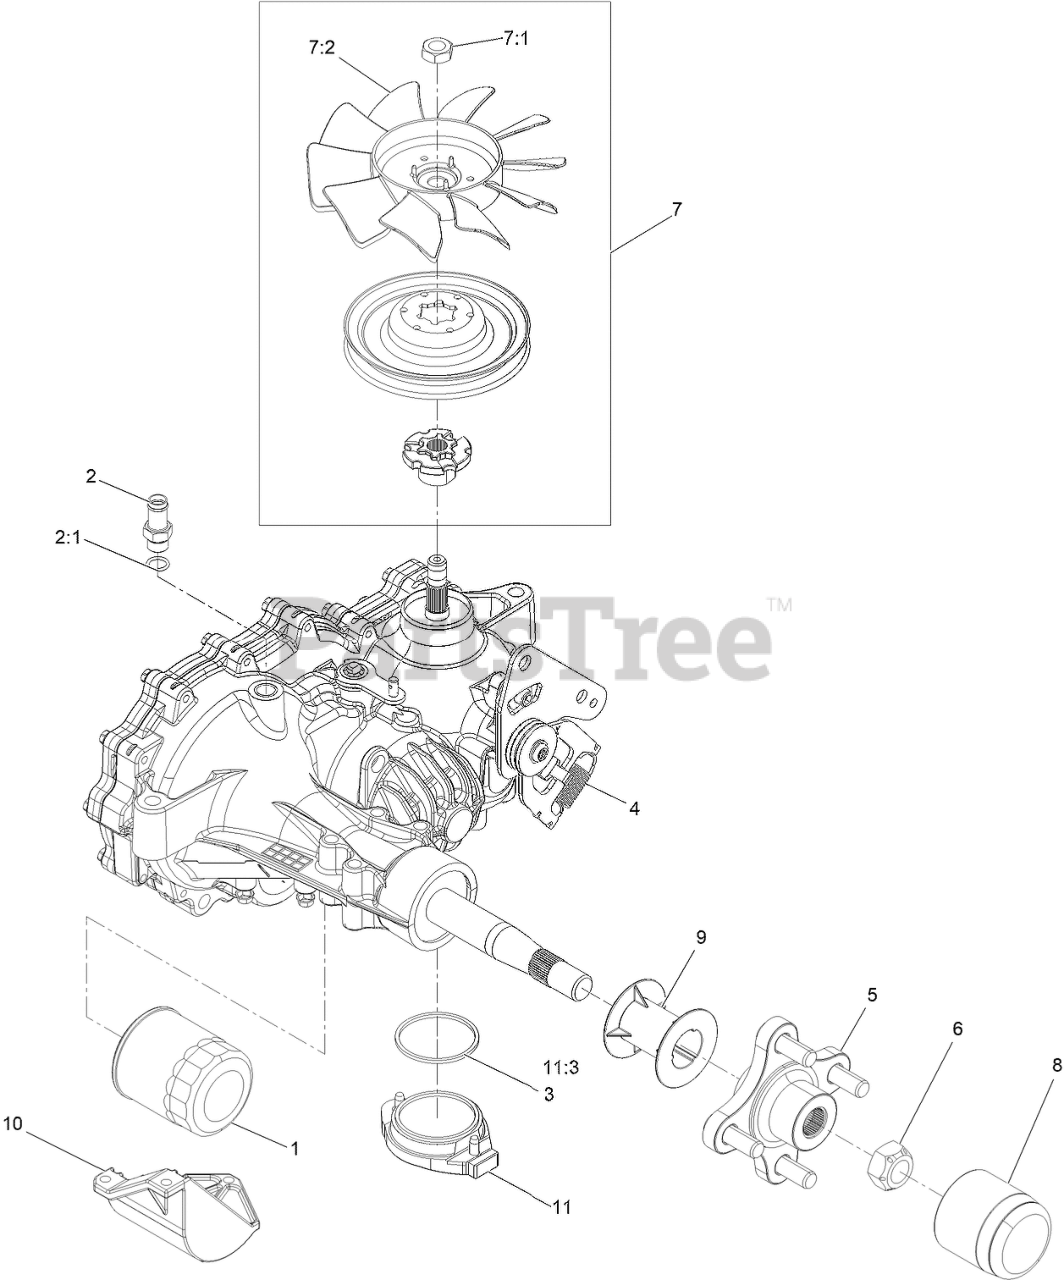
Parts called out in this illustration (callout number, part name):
1	ELEMENT-OIL FILTER, HYD
2	ADAPTER-STRAIGHT
2:1	O-RING
3	O RING-SEAL
4	SPRING-EXTENSION
5	HUB-OFFSET
6	NUT-HUB
7	Fan And Pulley Kit
8	CAP-AXLE, LONG
9	TUBE-AXLE
10	GUARD-FILTER, RH
11	CHARGE KIT
11:3	O RING-SEAL
99	BRAKE SHAFT SEAL KIT
